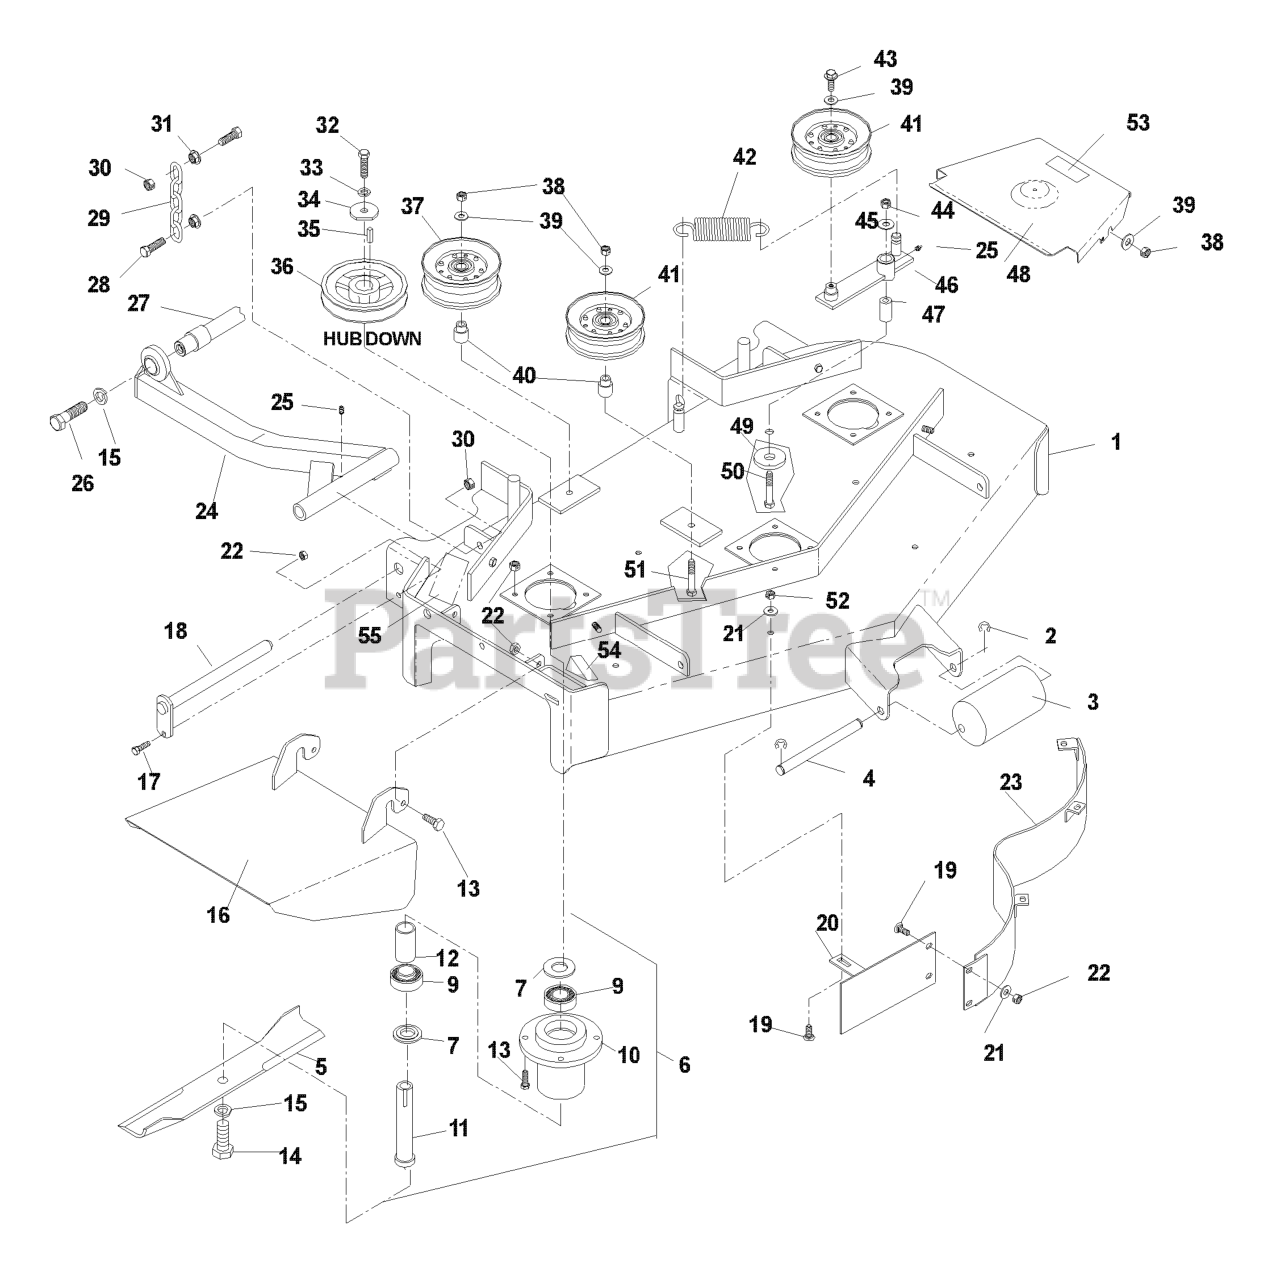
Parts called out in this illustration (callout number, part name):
1	DECK W/DECALS 42"
2	E-RING 1/2 (2 2)
5	BLADE OEM, 14-7/8
6	HOUSING, COMPLETE
7	MACHINERY BUSHING 10 GA.
9	BEARING
10	HOUSING, DIE CAST
11	SPINDLE SHAFT
13	HCS 5/16C X 1 1/4
14	HCS 5/8F X 1 1/4
15	LOCKWASHER 5/8
16	DISCHARGE CHUTE 42"
17	HCS 5/16C X 3/4
19	CARRIAGE BOLT 5/16C X 5/8"
20	CENTER BAFFLE
21	WASHER 5/16 FLAT
22	NUT 5/16 CTR. LOCK
23	MAIN BAFFLE
24	STRUT WLDMT - RT
24	STRUT SLDMT-LT
25	ZERK
26	HCS 5/8C X 2 GR.5
27	STRUT MOUNT WELDMENT
28	HCS 7/16C X 1 1/2
29	LIFT CHAIN
30	NUT 7/16C CENTERLOCK
31	NUT 7/16C WHIZ
32	HCS 7/16F X 1 1/2
33	WASHER 7/16 LOCK
34	SPINDLE WASHER
35	KEY 1/4 SQ X 1 1/8
37	IDLER PULLEY (TALL)
38	NUT 3/8-16 NYLOC
39	WASHER 3/8 FLAT
40	IDLER BUSHING
41	IDLER PULLEY
43	4CS 3/8C X 1 SERRATED HEAD
44	NUT 1/2-13 HEX NYLOC ZD
45	WASHER 1/2 FLAT
47	PIVOT BUSHING
48	BELT SHIELD
49	WASHER, SUPPORT
50	HCS 1/2C X 3 1/4
51	SCREW 3/8C X 2 3/4 HEX CAP
52	NUT 5/16C CENTERLOCK
53	DECAL, NO STEP
54	DECAL, CPSC
55	DECAL, DANGER
